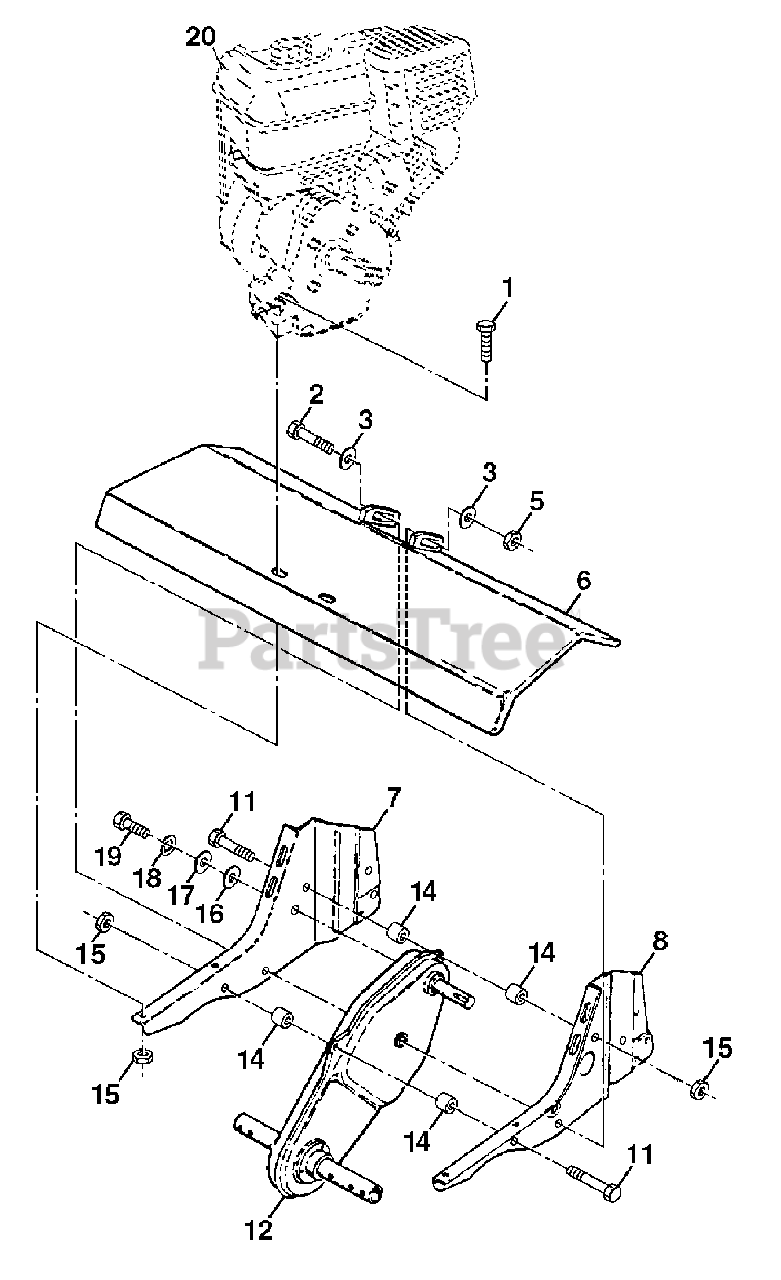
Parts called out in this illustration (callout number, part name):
1	Bolt, Hex 5/16-18 x 1-1/2 Gr. 2
2	Bolt, Hex, Fin 3/8-16 x 3-1/4
3	Washer 13/32 x 13/16 x 11
5	Locknut, Hex, w/washer 3/8-16
6	Shield, Tine
7	Bracket, Engine, R.H.
8	Bracket, Engine, L.H.
11	Bolt, Hex 5/16-18 x 2-3/4
12	Transmission
14	Spacer, Split
15	Nut Lock Hex Flg
16	Washer 9/32 x 7/8 x 12 Ga.
17	Washer 9/32 x 1-1/4 x 16 Ga.
18	Washer, Lock 1/4
19	Bolt, Hex 1/4-28 x 3/4 Gr. 5
